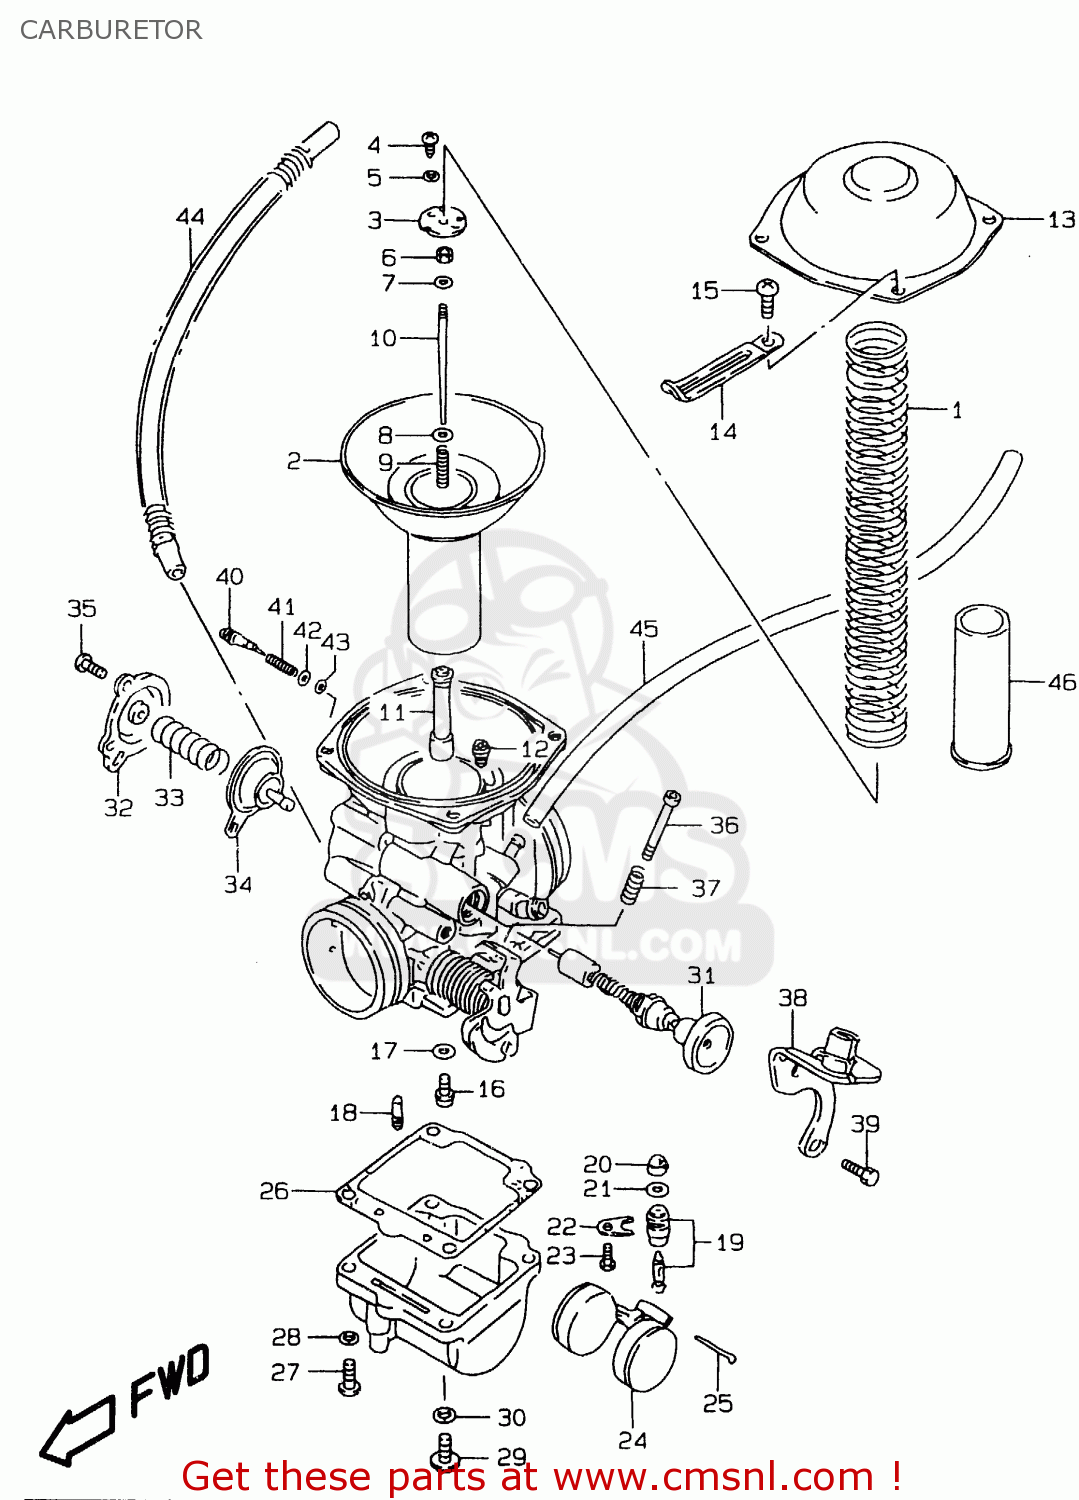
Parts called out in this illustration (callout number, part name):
1	SPRING
2	DIAPHRAGM ASSY
3	PLATE
4	SCREW
5	WASHER,LOCK
6	RING
7	CLIP,NEEDLE
8	WASHER
9	SPRING
10	NEEDLE,JET
11	JET,NEEDLE(X-7)
12	JET(45)
13	COVER
14	CLAMP(L:65)
15	SCREW
16	JET,MAIN(125)
17	WASHER
18	JET,PILOT(47.5)
19	VALVE ASSY,NEEDLE
20	FILTER
21	O-RING,NEEDLE VALVE
22	PLATE
23	SCREW 4X6
24	FLOAT
25	PIN,FLOAT
26	GASKET,FLOAT CAHMBER (NAS)
27	SCREW
28	LOCK,WASHER
29	PLUG,DRAIN
30	GASKET (NAS)
31	PLUNGER ASSY
32	COVER
33	SPRING
34	DIAPHRAGM ASSY
35	SCREW
36	ADJUSTER
37	SPRING
38	BRACKET ASSY
39	SCREW
40	SCREW,AIR
41	SPRING
42	WASHER
43	O RING,PILOT AIR SCREW
44	HOSE ASSY
45	HOSE(5X8.2X600)
46	PIPE
